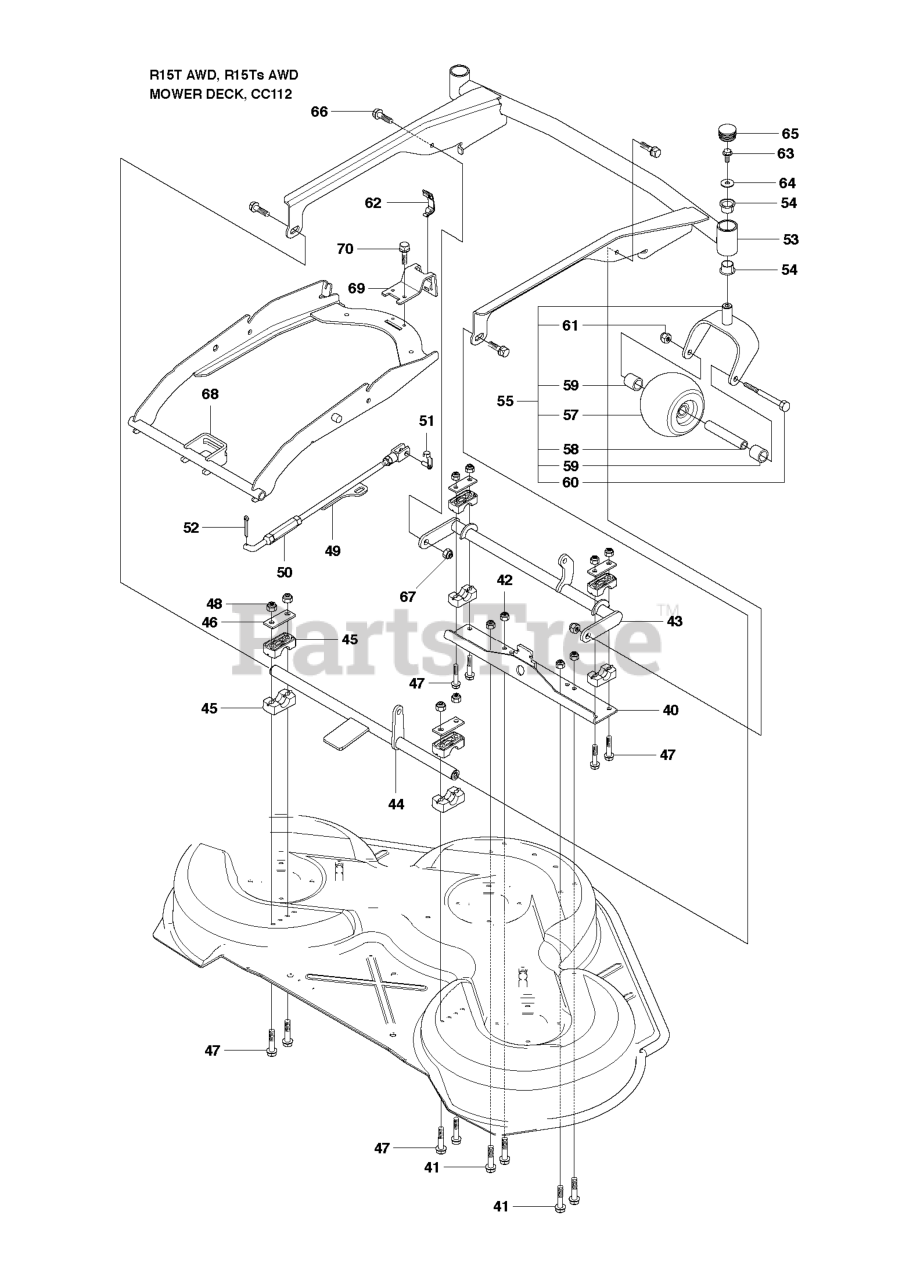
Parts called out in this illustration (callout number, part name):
42	LOCKNUT M8
48	LOCKNUT M8
49	PARALLELL ROD ASSY
50	PARALLEL ROD
51	RETAINER
53	DECK FRAME
55	PIVOT WHEEL ASSY
57	DECK ROLLER, FRONT
61	NUT
62	CLIP GRAY
67	LOCKNUT M8
68	DECK ATTACHMENT
70	SCREW
